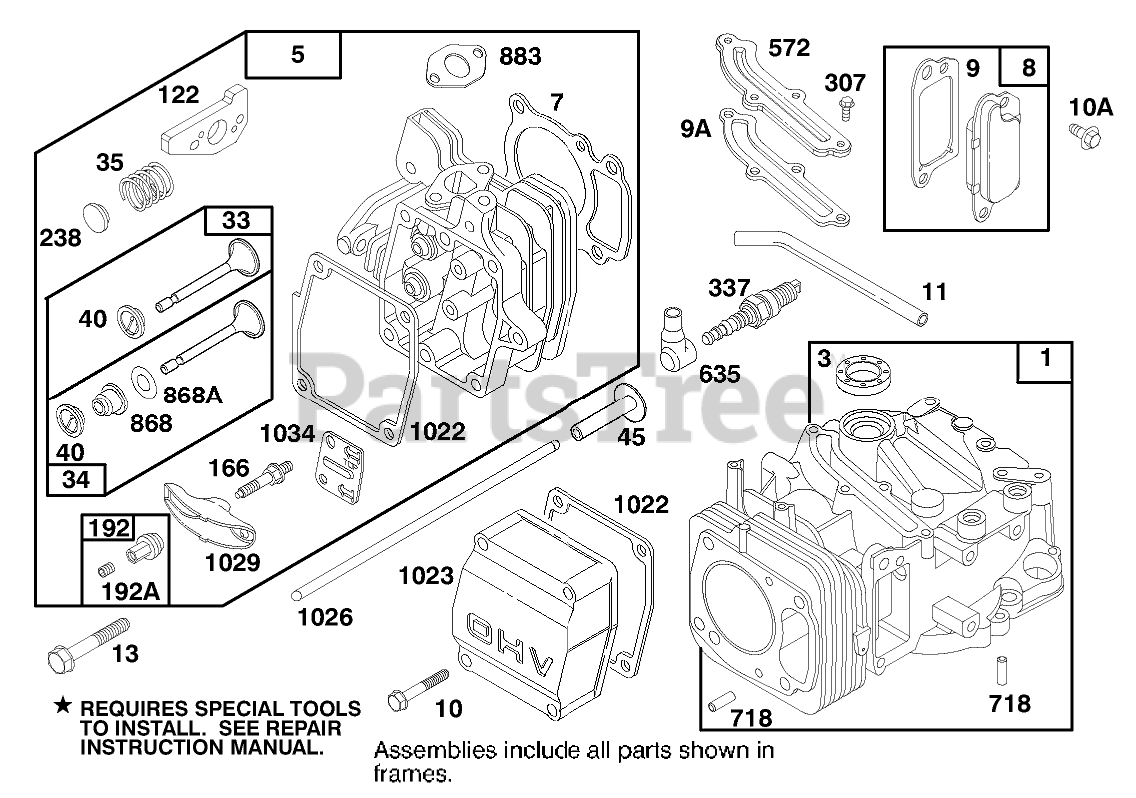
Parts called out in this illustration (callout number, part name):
1	CYLINDER ASSEMBLY
3	SEAL - OIL
5	CYLINDER HEAD
7	CYLINDER HEAD GASKET
8	Breather Assy
9	BREATHER GASKET
9A	GASKET-BREATHER
10	HEX HEAD SCREW
10A	HEX HEAD SCREW
11	TUBE - BREATHER
13	CYLINDER HEAD SCREW
33	EXHAUST VALVE
34	INTAKE VALVE
35	VALVE SPRING
40	SPRING RETAINER
45	VALVE TAPPET
122	ADAPTER ASSEMBLY
166	ROCKER ARM STUD
192	NUT - HEX SPECIAL
192A	SCREW SET
238	VALVE CAP
307	SCREW - SEM
337	PLUG-SPARK
572	BAFFLE - CYCLINDER
635	SPARK PLUG ELBOW
718	DOWEL - SLEEVE
868	SealAssy-Valve
868A	Seal-Valve
883	EXHAUST GASKET
1022	ROCKER COVER GASKET
1023	COVER - VALVE
1026	PUSH ROD
1029	ROCKER ARM
1034	PUSH ROD GUIDE
